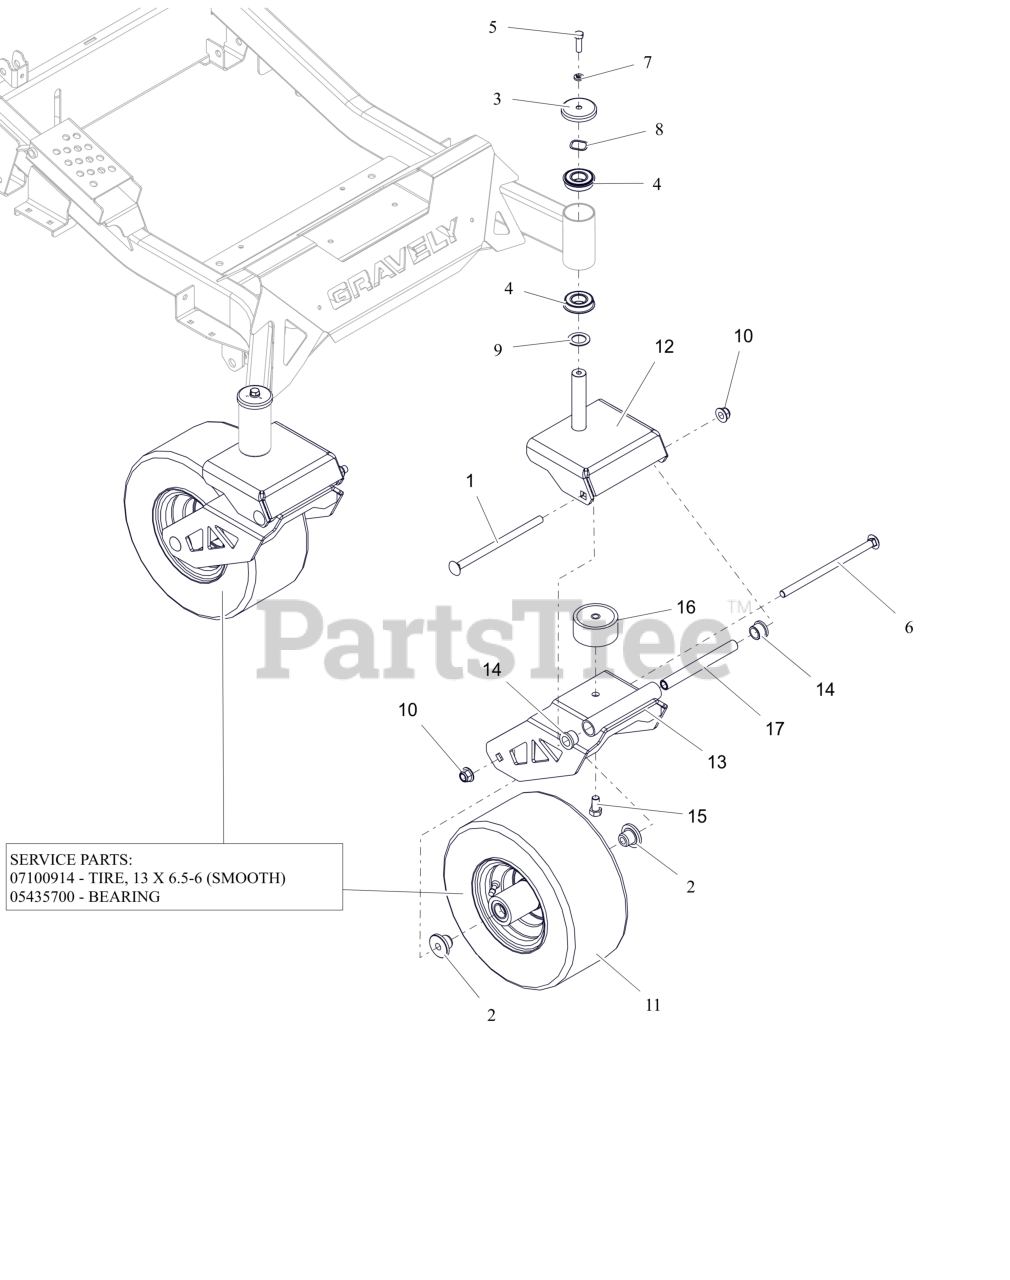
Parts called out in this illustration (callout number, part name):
1	BLT, RHSN .50-13X8.50 G5 ZCC
2	SPACER, FRONT WHEEL
3	SHIELD, AXLE BEARING
4	BEARING, BALL -2.000 OD X 1.000 ID X .5625 W/RING
5	BLT, HEX .38-16X1.25 G5 ZCC
6	BTL,RHSN .500-13 X 9 G5 ZCC
7	WSHR, LK-HVY .375X.115 ZCC
8	WSHR-WAVE 1.0X1.25X.028 .145FH
9	WSHR-HRD-THRS 1.007X1.542X.062
10	NUT,NYL-FLG .50-13 GF ZCC
11	ASM, WHL/TIRE 13X6.50-6
11	TIRE, 13X6.50-6 SMOOTH
11	BRG, 25MM ID X 52MM OD X 15MM
12	WLDMT, UPPER SUSPENSION (RED)
13	WLDMT, LOWER SUSPENSION (RED)
14	BUSHING, FLANGE .75X.75X1.0
15	BLT, HEX .50-13X1.00 G5 ZCC
16	SPCR, RUBBER SUSPENSION
17	ROD, FORK PIVOT
